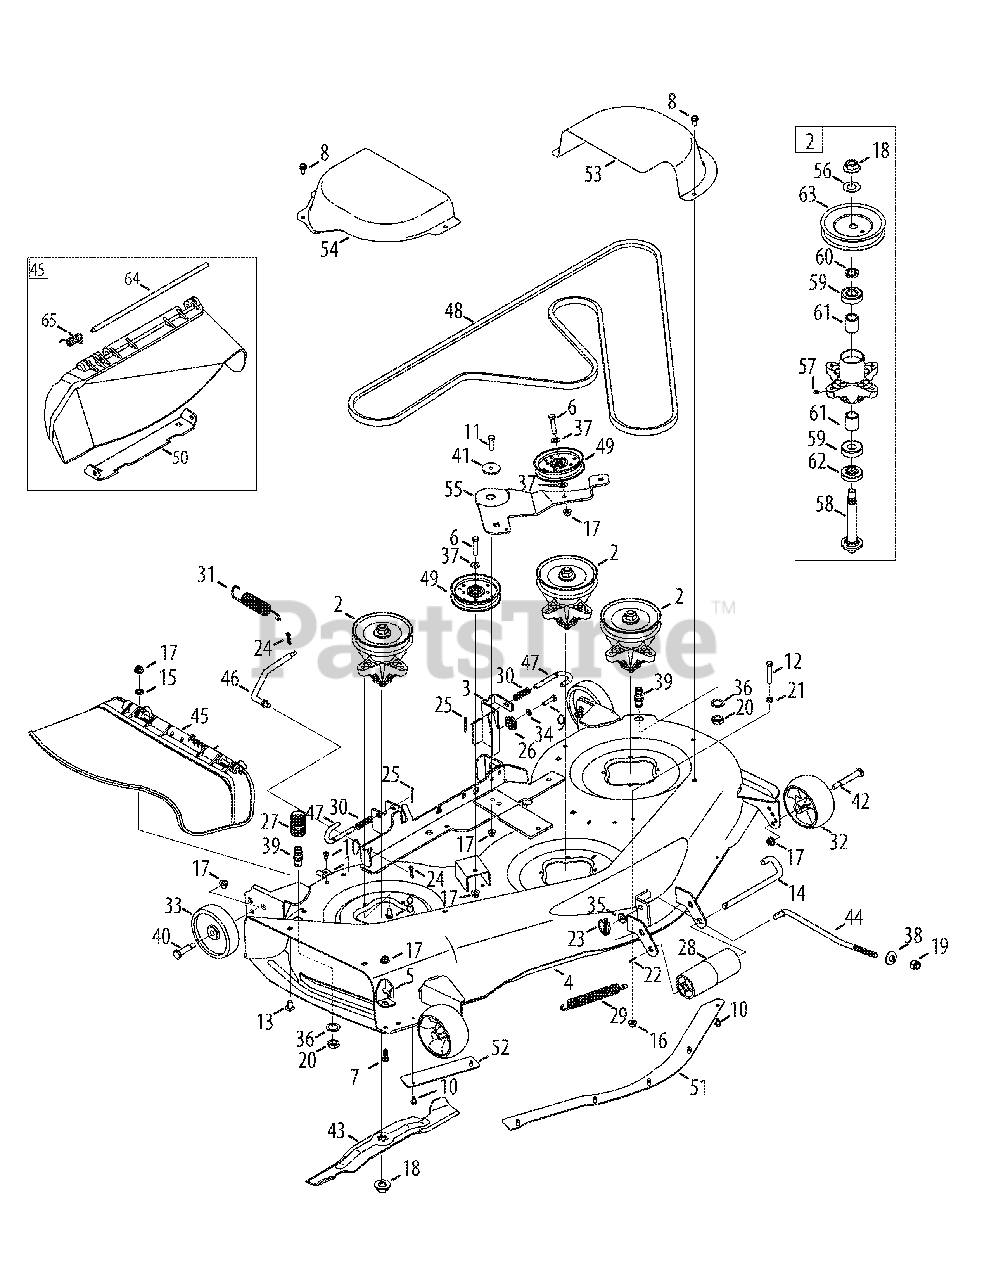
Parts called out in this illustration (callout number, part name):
1	Hook Retainer Bracket
2	Pulley Spindle Assembly, 5.39
3	Deck Hanger Bracket Assembly
4	Deck
6	Hex Screw, 3/8-16:1.75
7	Hex Screw, 3/8-16:1.00
8	Taptite Screw, 5/16-18:.750
9	Hex Screw, 5/16-18:1.25
10	Taptite Screw, 1/4-20:0.500
11	Hex Screw, 3/8-16:1.25
12	Hex Screw, 5/16-18:2.0
13	Carriage Bolt, 3/8-16:0.75
14	Roller Pin, 1/2 DIA x 7.31 LG
15	Push Nut, 3/8
16	Flangelock Nut, 5/16-18
17	Flangelock Nut, 3/8-16
18	Flange Nut, 5/8-18
19	Flexlock Nut, 1/2-13
20	Hex Nut, M16-1.5 DIN 936
21	Hex Nut, 5/16-18:GR5
22	Cotter Pin, 3/32:1.0
23	Lynch Pin, .1875
24	Bow-Tie Cotter Pin
25	Cotter Pin, 1/8 x 1.25
26	Deck Adjustment Gear
27	Water Nozzle Adaptor
28	Front Roller
29	Extension Spring, .94 DIA. x 6.74 LG
30	Compression Spring, .535 OD x 1.751 LG
31	Extension Spring, 1.15 OD x 5.99 LG
32	Front Deck Wheel
33	Rear Deck Wheel
34	Lock Washer, 5/16
35	Flat Washer, .531 x 1.25 x .100
36	Lock Washer, 5/8
37	Flat Washer, .406 x .875 x .059
38	Bell Washer, .63 x 1.25 x .18
39	Water Nozzle
40	Shoulder Bolt, .496 x 1.525:3/8-16
41	Shoulder Spacer, .8840 x .190
42	Shoulder Bolt, .496 x 2.50:3/8-16
44	Front Deck Lift Rod
45	Chute Assembly
46	Deck Sway Rod
47	Deck Release Handle Rod
48	V Belt
49	Idler Pulley, 4.25"DIA
50	Chute Bracket
51	Center Skirt
52	RH Skirt
53	LH Belt Cover
54	RH Belt Cover
55	Idler Bracket
56	Flat Washer, .760 x 1.50 x .120
57	Lube Fitting
58	Spindle Shaft
59	Ball Bearing, .787ID x 1.85
60	Spacer, .790 ID x 1.25 OD x .175
61	Spacer, .80 x 1.10 x 1.322
62	Spacer, .79 x 1.82 x .55
63	Deck Pulley
64	Hinge Pin
65	Torsion Spring
